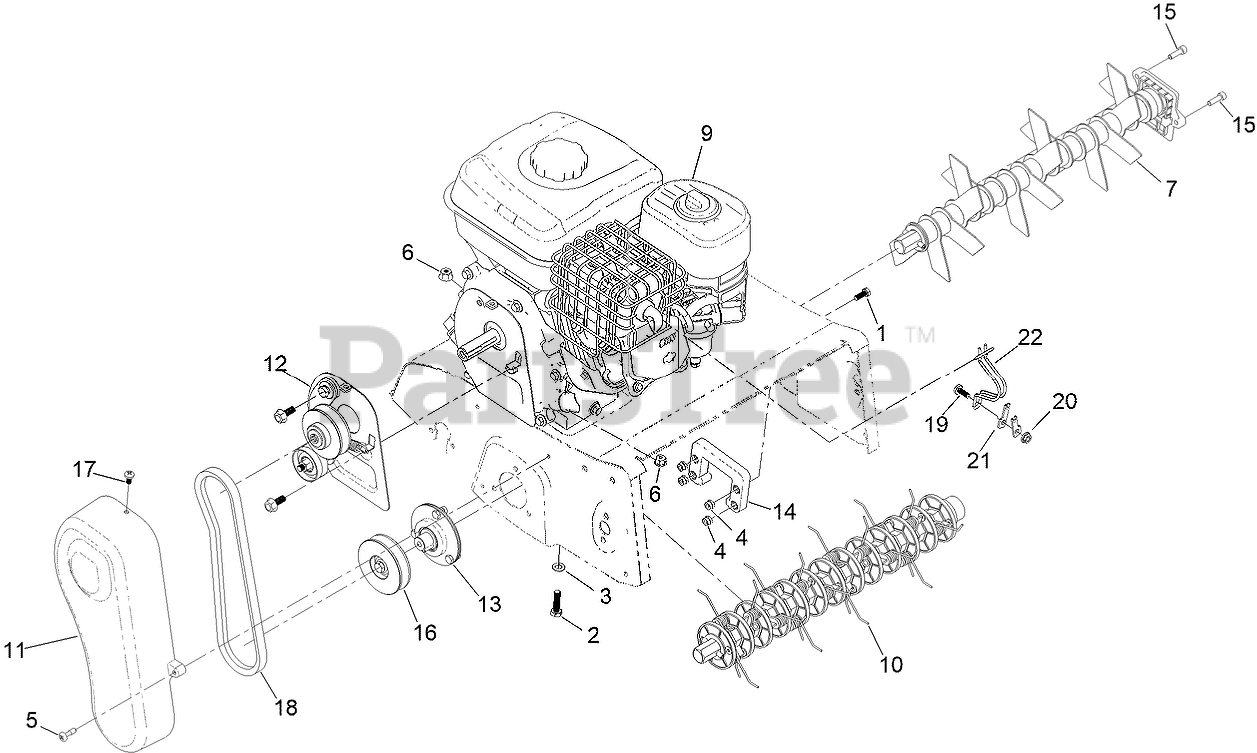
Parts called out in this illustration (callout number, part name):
1	BOLT-HEX
2	SCREW-HH
3	WASHER
4	NUT-NYLOC
6	NUT-LOCK, FLANGE
7	SCARIFIER BLADE SHAFT ASSY
10	AERATOR ASSY
11	GUARD-PULLEY
12	PLATE-PULLEY, ENGINE
13	SHAFT PULLEY COUPLER ASSY
14	DOCK-SHAFT, TINE
15	SCREW-SOCKET CAP HEAD
16	PULLEY-SHAFT, TINE
17	SCREW-PAN HEAD
19	CROSS SCREW M6X16
20	M6 HEX NUT
21	EXHAUST GUARD BRACKET
22	GUARD-EXHAUST
